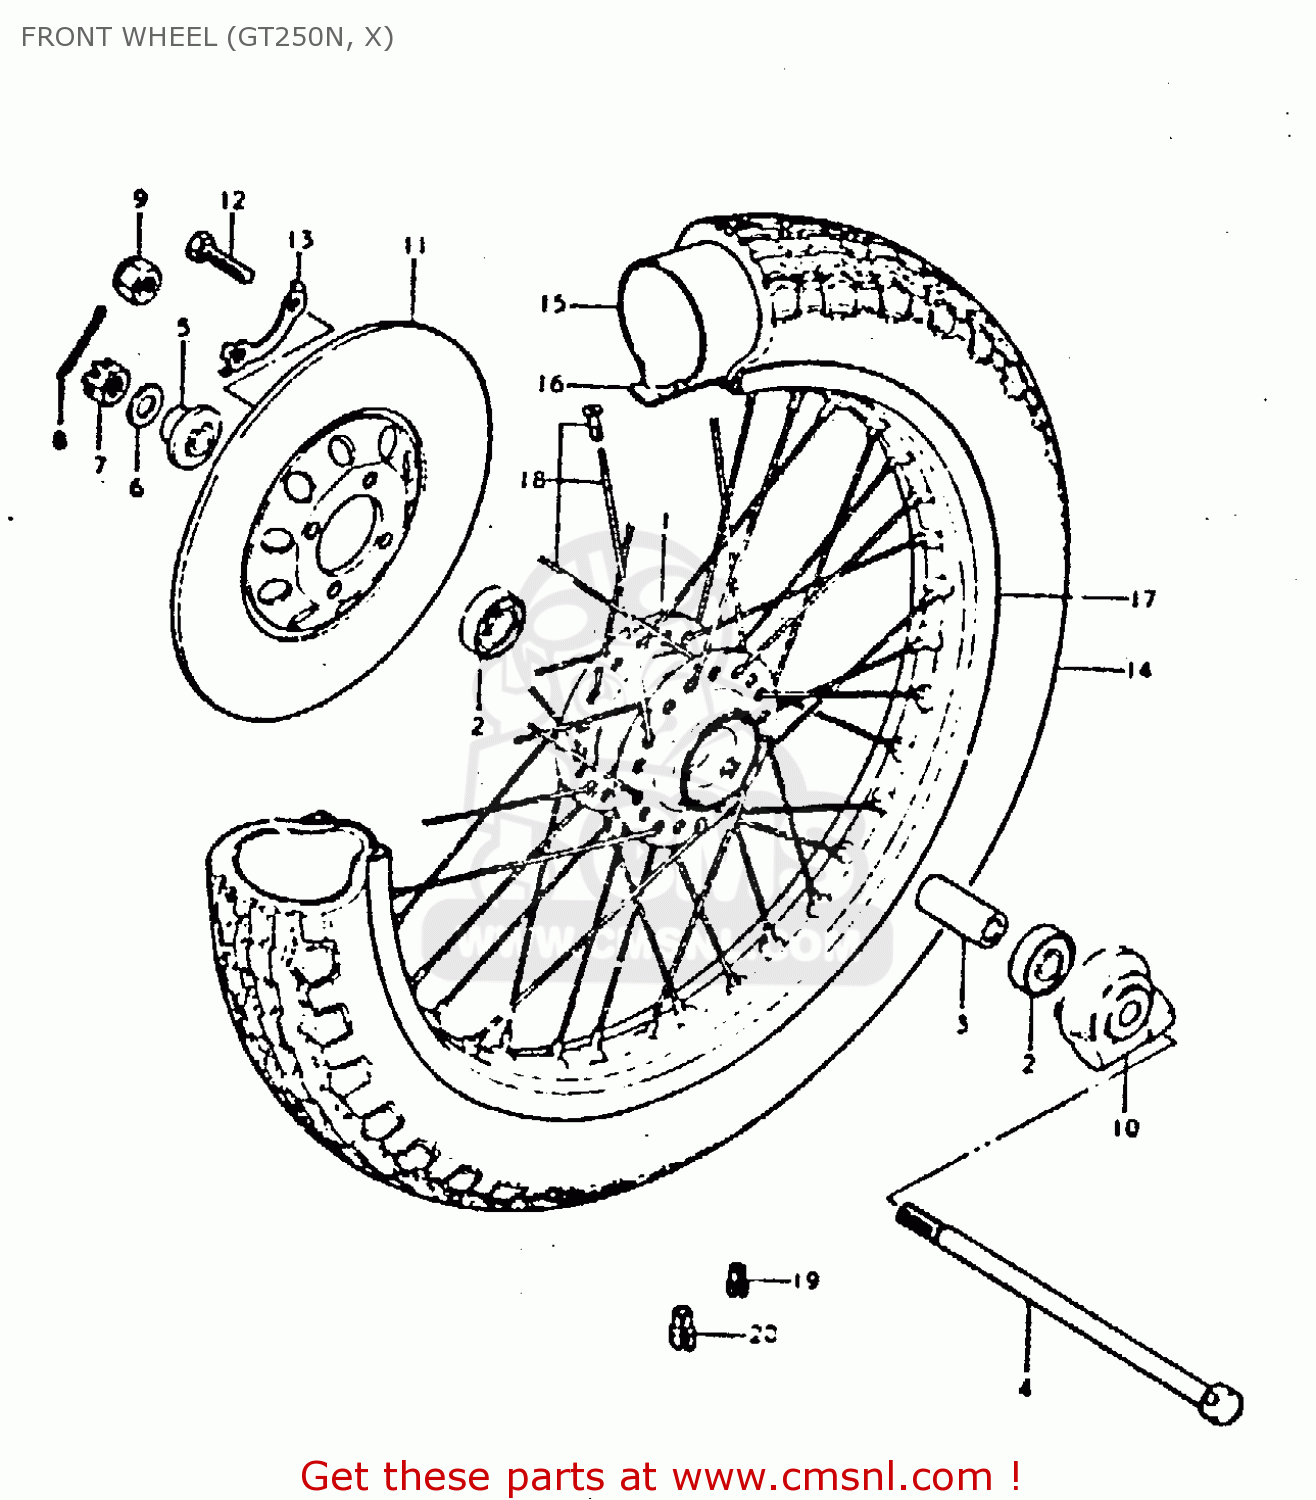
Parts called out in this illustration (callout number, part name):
1	HUB,FRONT
2	BEARING
3	SPACER (12.6X19X52)
4	AXLE, FRONT
5	SPACER,FR AXLE,L
6	WASHER
7	NUT 12MM
8	COTTER PIN
10	BOX ASSY,SPEEDOMETER GEAR
11	DISC,BRAKE
12	BOLT(8X25)
13	WASHER
14	TIRE,FRONT
15	TUBE,INNER
16	PROTECTOR,WHEEL,INNER
17	RIM,FRONT WHEEL
18	SPOKE SET,FRONT
19	BALANCER,WHEEL (B)
20	BALANCER,WHEEL (30G)
